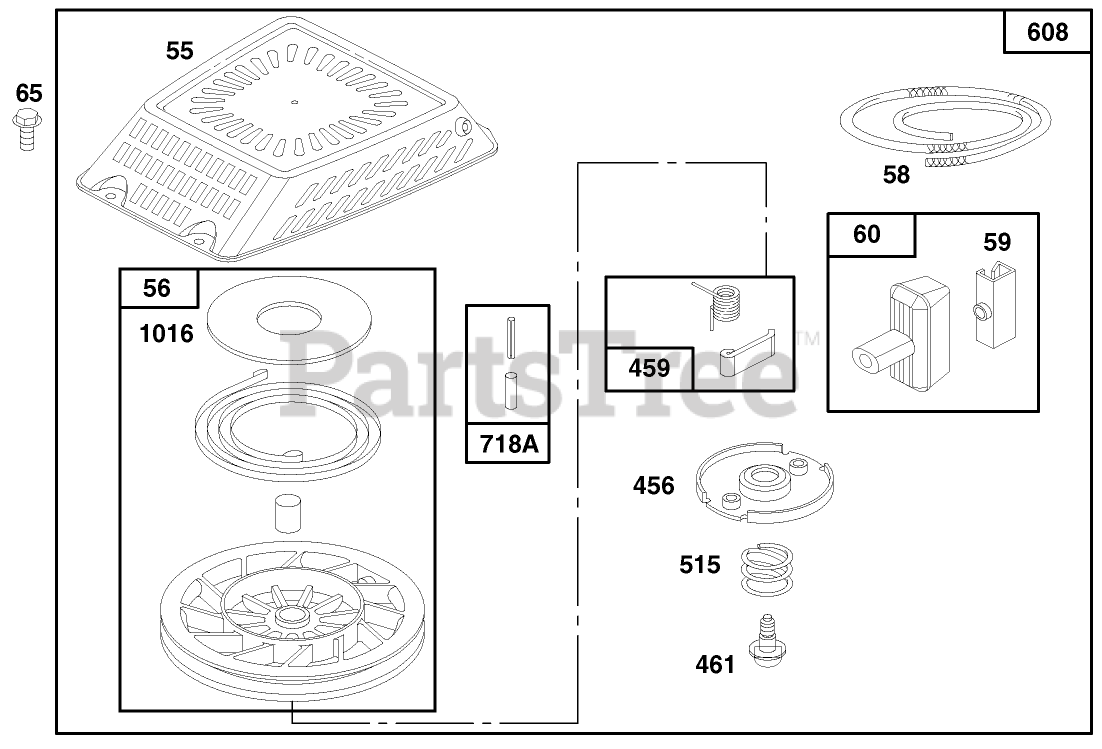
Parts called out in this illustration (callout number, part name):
59	INSERT-HANDLE, REWIND
456	RETAINER - SPRING
515	SPRING - RETAINER
